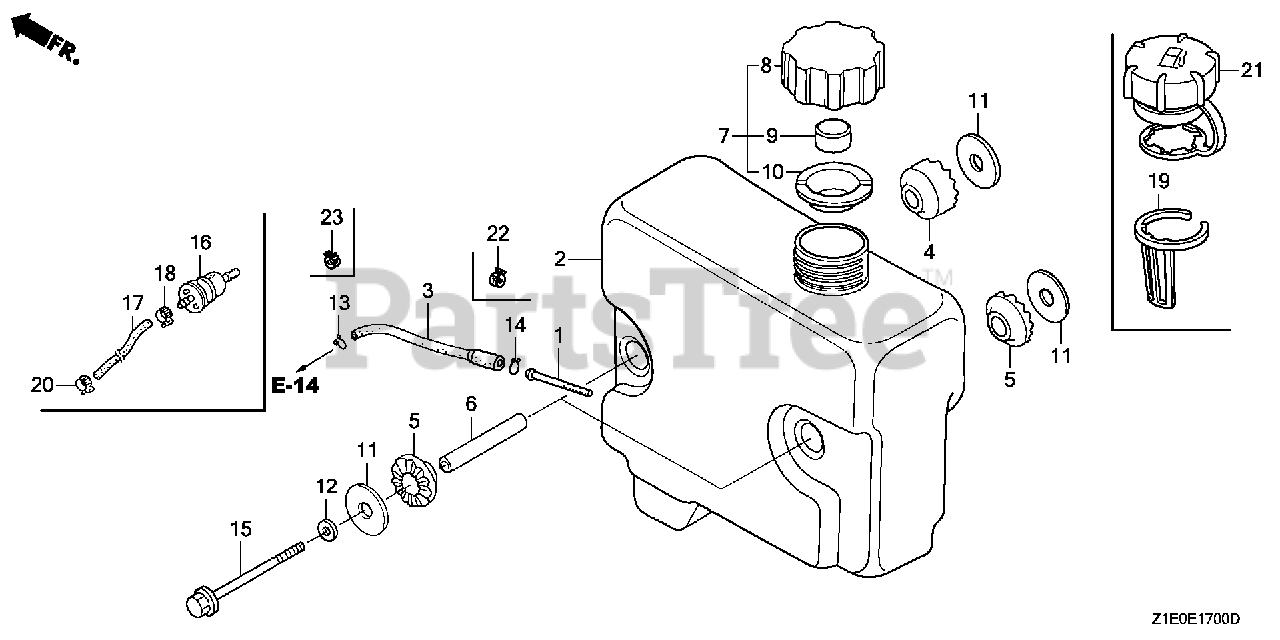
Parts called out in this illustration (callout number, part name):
1	FILTER, FUEL
2	TANK, FUEL
3	TUBE, FUEL (FKM)
4	RUBBER B, TANK MOUNTING
5	RUBBER B, TANK MOUNTING
6	COLLAR, TANK SETTING
11	WASHER, TANK MOUNTING
12	WASHER, PLAIN (8MM)
15	BOLT, FLANGE (8X95)
19	GAUGE, FUEL LEVEL
21	CAP ASSY., FUEL TANK
22	CLIP, TUBE (10.5MM)
23	CLIP, TUBE (D8)
